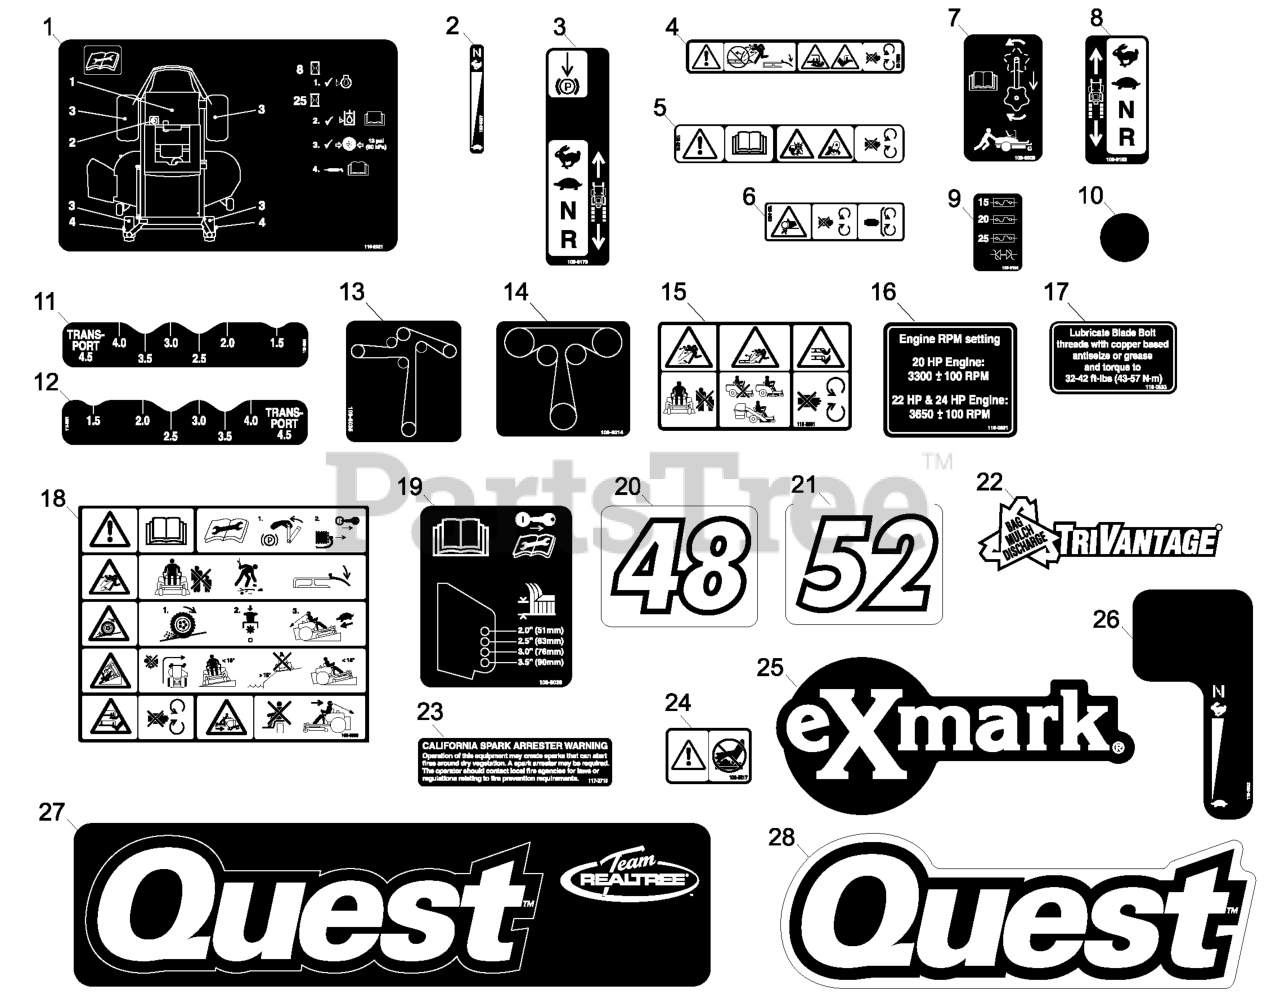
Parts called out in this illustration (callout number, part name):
1	DECAL-SERVICE AID
2	DECAL,THROTTLE/CHOKE
3	DECAL-CONTROL BRAKE
4	DECAL-DANGER
5	DECAL-DANGER
6	DECAL-WARNING, BELT SHIEL
7	DECAL-DRIVE RELEASE
8	DECAL-MOTION CONTROL
9	DECAL-FUSE BLOCK
10	DECAL-HOLE COVER
11	DECAL,HEIGHT OF CUT
12	DECAL,HEIGHT OF CUT
13	DECAL-ROUTING, BELT
14	DECAL-ROUTING, BELT
15	DECAL-DANGER
16	DECAL,ENGINE RPM
17	DECAL,BLADE TORQUE
18	DECAL-SAFETY
19	DECAL-ROLLER, ANTI-SCALP
20	DECAL,DECK 48
21	DECAL,DECK 52
23	DECAL-ARRESTER, SPARK
24	DECAL-WARNING
25	DECAL,EXMARK LOGO
26	DECAL,THROTTLE CHOKE 42
27	DECAL,QUEST REALTREE
28	DECAL,QUEST LOGO
